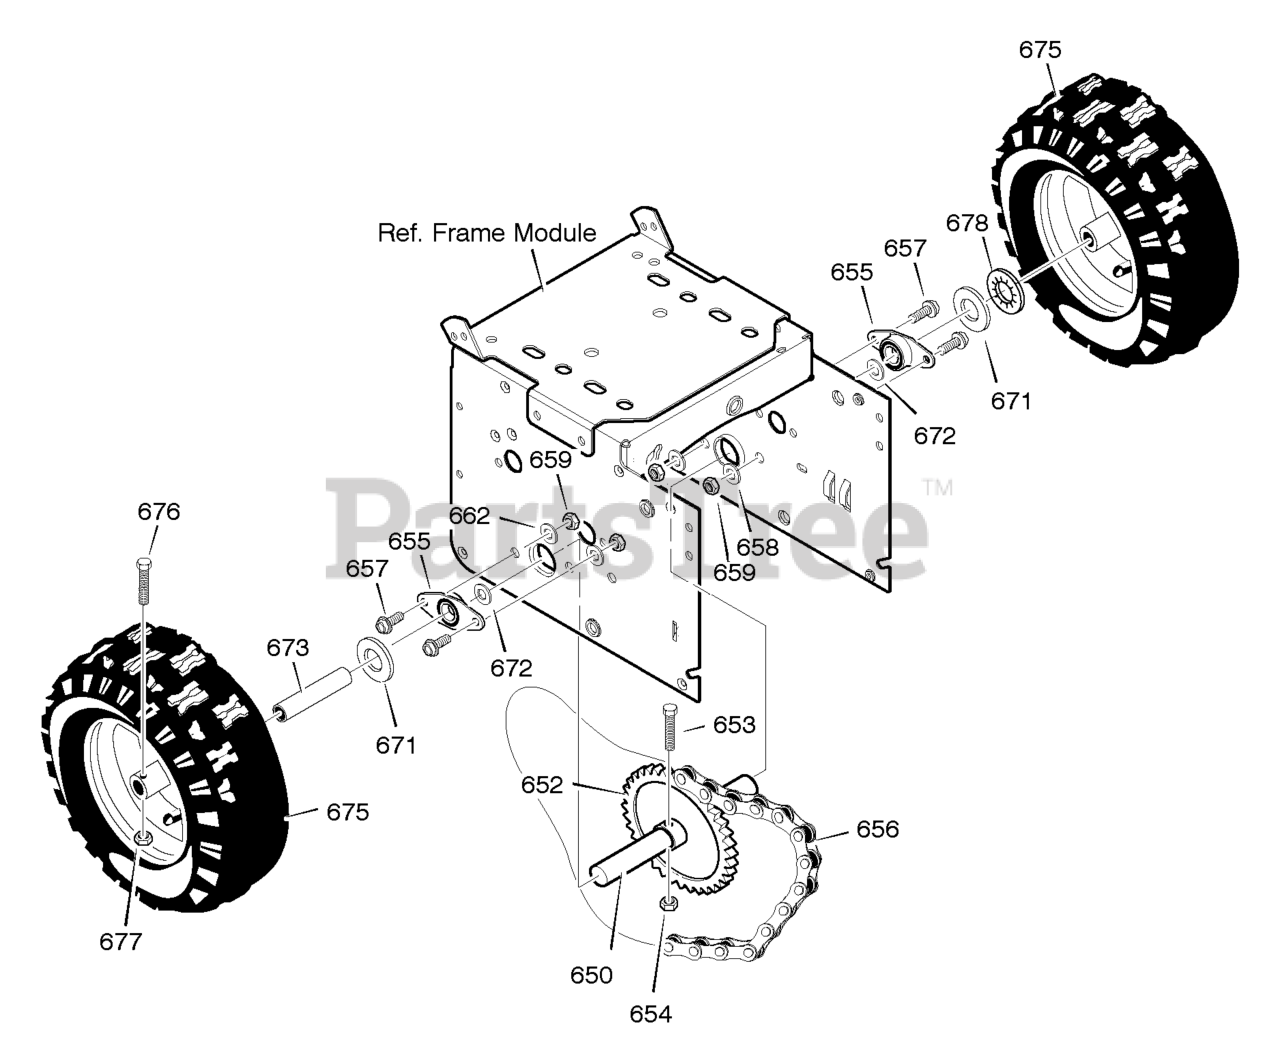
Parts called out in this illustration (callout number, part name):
650	SHAFT, AXLE
652	SPRKT & HUB
653	SCREW, 1/4-20X1.75
654	NUT, 1/4-20 HEX NYLOCK
655	RETAINER & BEARING ASSY
657	SCREW, 3/8"-16x.75
658	WASHER, LOCK
659	NUT, 3/8"-16
671	WASHER, FLAT
673	BUSHING, WHEEL
675	TIRE & RIM -Right
676	SCREW, 1/4-20X1.75 HH
677	NUT, 1/4-20 HEX NYLOCK
678	RING, RET
680	TIRE & RIM -Left
